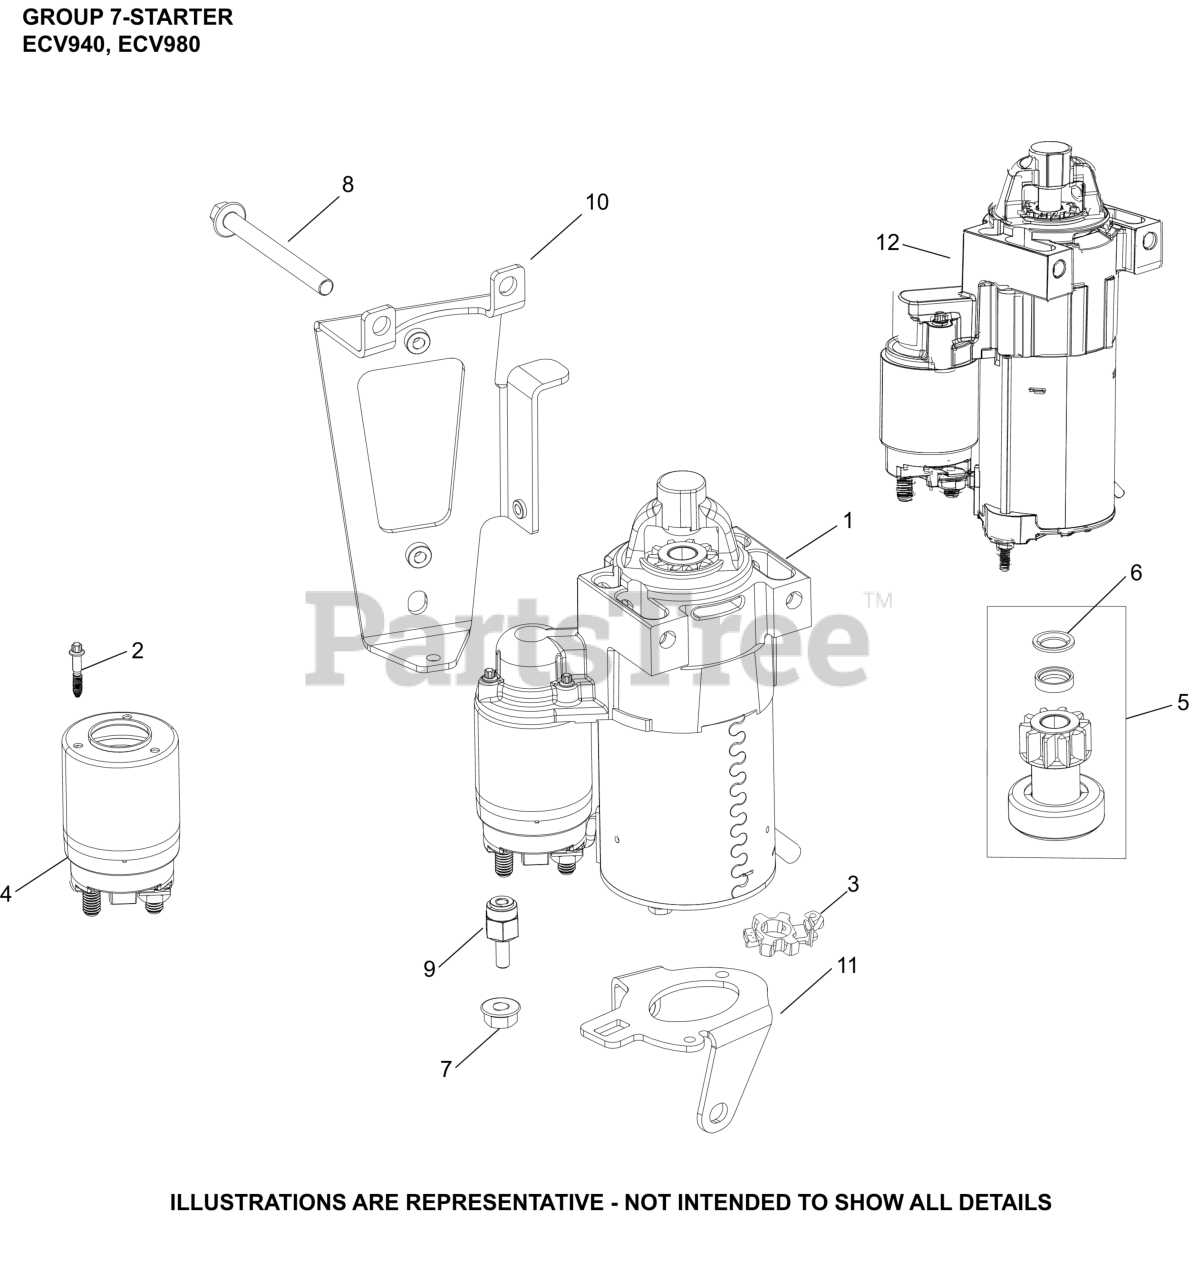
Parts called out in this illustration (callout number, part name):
7	NUT, FLG M8X1.25
8	SCREW, FLG M8X1.25X80
NI	STARTER, SOLENOID SHIFT
